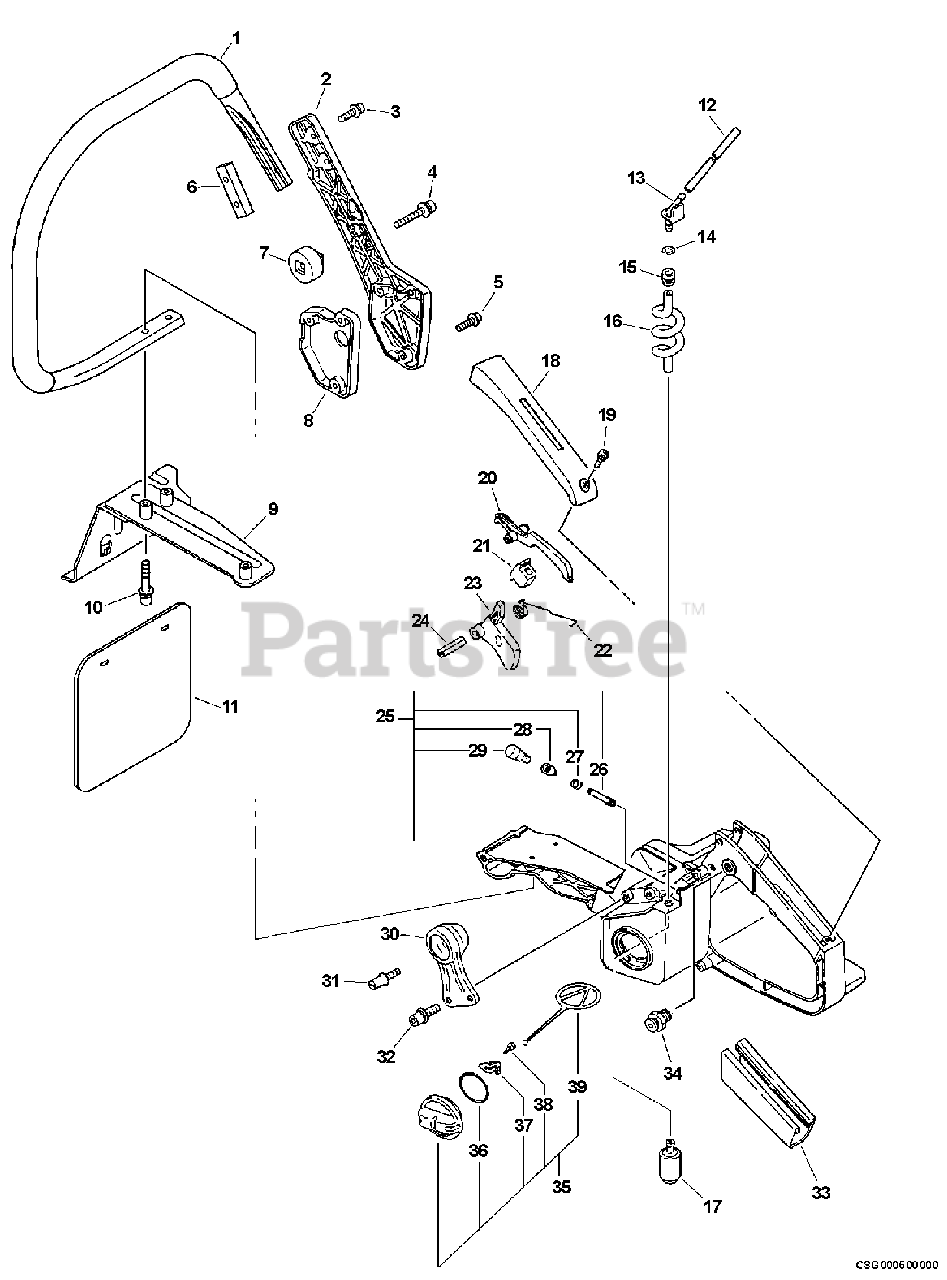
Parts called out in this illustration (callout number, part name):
1	HANDLE - FRONT
2	BRACKET, HANDLE - OUTER
3	SCREW - 5X20
4	SCREW - 5X30
5	SCREW - 5X35
8	SPACER
9	FIXTURE, HANDLE
10	SCREW - 5X30
11	SHIELD
12	PIPE - 3X6X100 -- BLACK
13	CONNECTOR, PIPE
14	CLIP - 6.5
15	GROMMET
16	PIPE - BLACK
17	FILTER, FUEL
18	COVER, HANDLE
19	SCREW - 4X14
20	LEVER, TRIGGER LOCKOUT
22	SPRING, TRIGGER
23	TRIGGER, THROTTLE
24	PIN - SPRING -- 5X25
25	HANDLE - REAR
26	PIPE - VENT
27	CLIP - 5.5
28	COVER, VENT
29	VENT, FUEL TANK
32	SCREW - 5X14
33	GRIP, HANDLE
34	LATCH, THROTTLE
35	CAP ASSY
36	O-RING - 29
37	RETAINER
38	SCREW - 3X8
39	CONNECTOR, CAP
